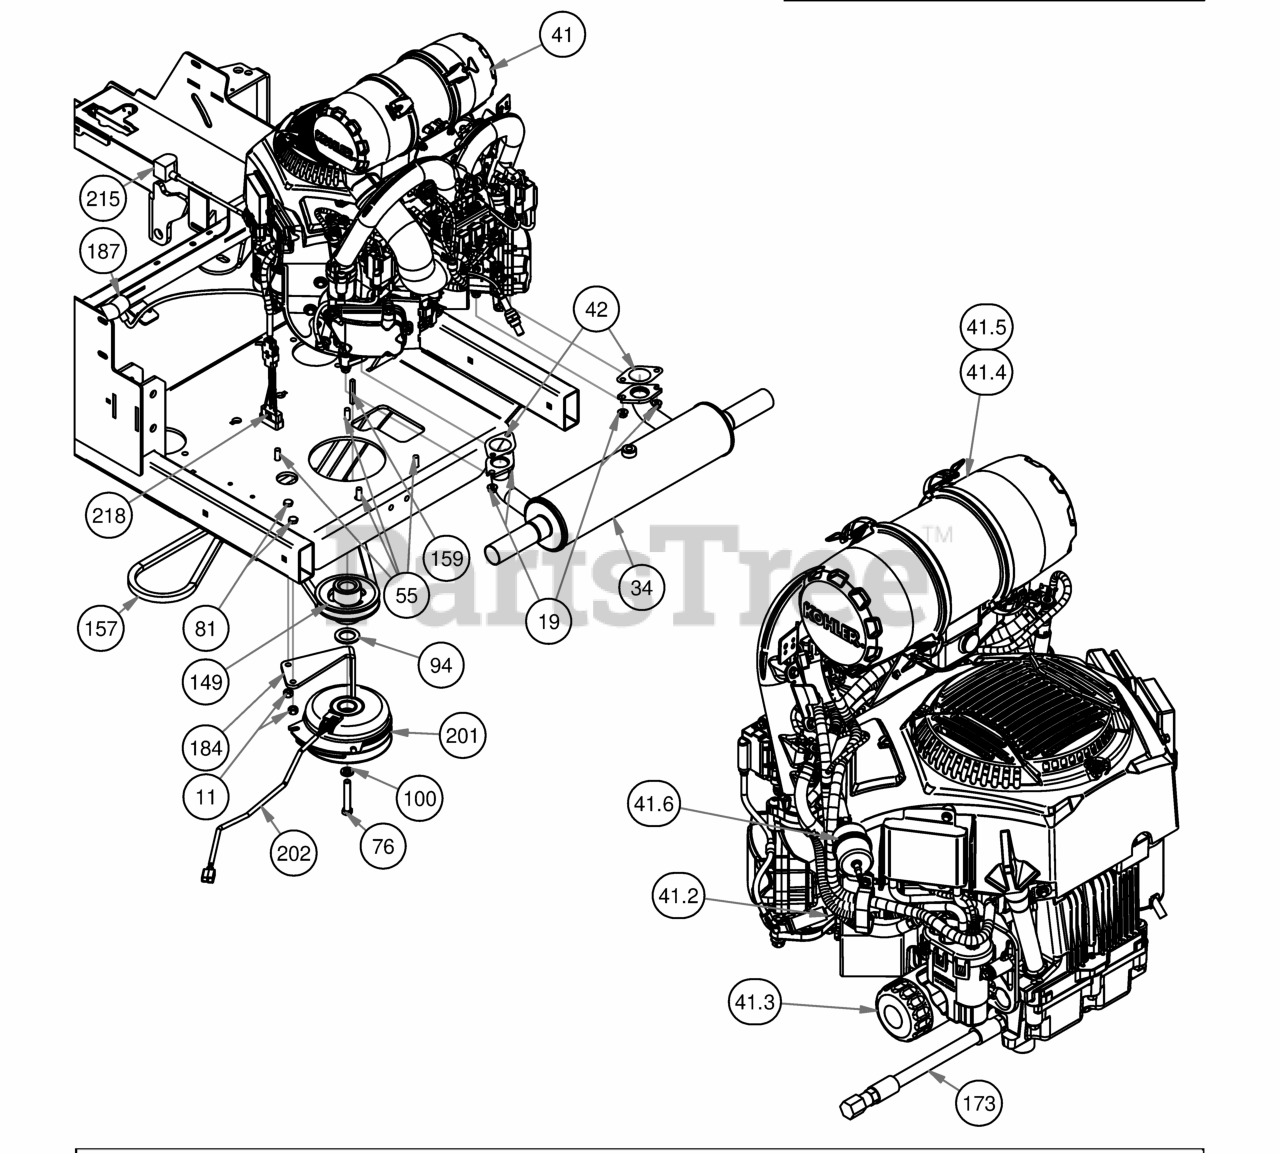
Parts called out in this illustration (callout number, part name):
11	3/8" Hex Nut
19	M8 Flange Nut for Kohler Exhaust
34	Muffler for 33Hp 824cc Kohler Engine
41	824cc EFI Kohler
41.2	Spark Plug
41.3	Oil Filter
41.4	Canister Air Filter- Inner
41.5	Canister Air Filter- Outer
41.6	25/26 HP Kohler Fuel Filter
42	Exhaust Gasket for 824EFI Kohler
55	3/8 x 1 1/8 bolt
76	7/16" x 2 1/2" Hex Bolt
81	3/8" x 1" Hex Bolt
94	1 1/8" Flat Spacer
100	7/16" Lock Washer
149	4 3/4 Motor Pulley
157	2019 Rogue Pump Belt 68"
159	1/4 x 2 Square key Stock
173	Oil drain Hose
184	PTO Engager Holder
187	24" Red Battery Cable
201	Clutch Assembly
202	Clutch Pigtail
203	2019 Veritical Suspension Frame
215	Starter Cable
218	2019 Harness Adaptor - Vanguard 37 EFI Vert/Horiz
